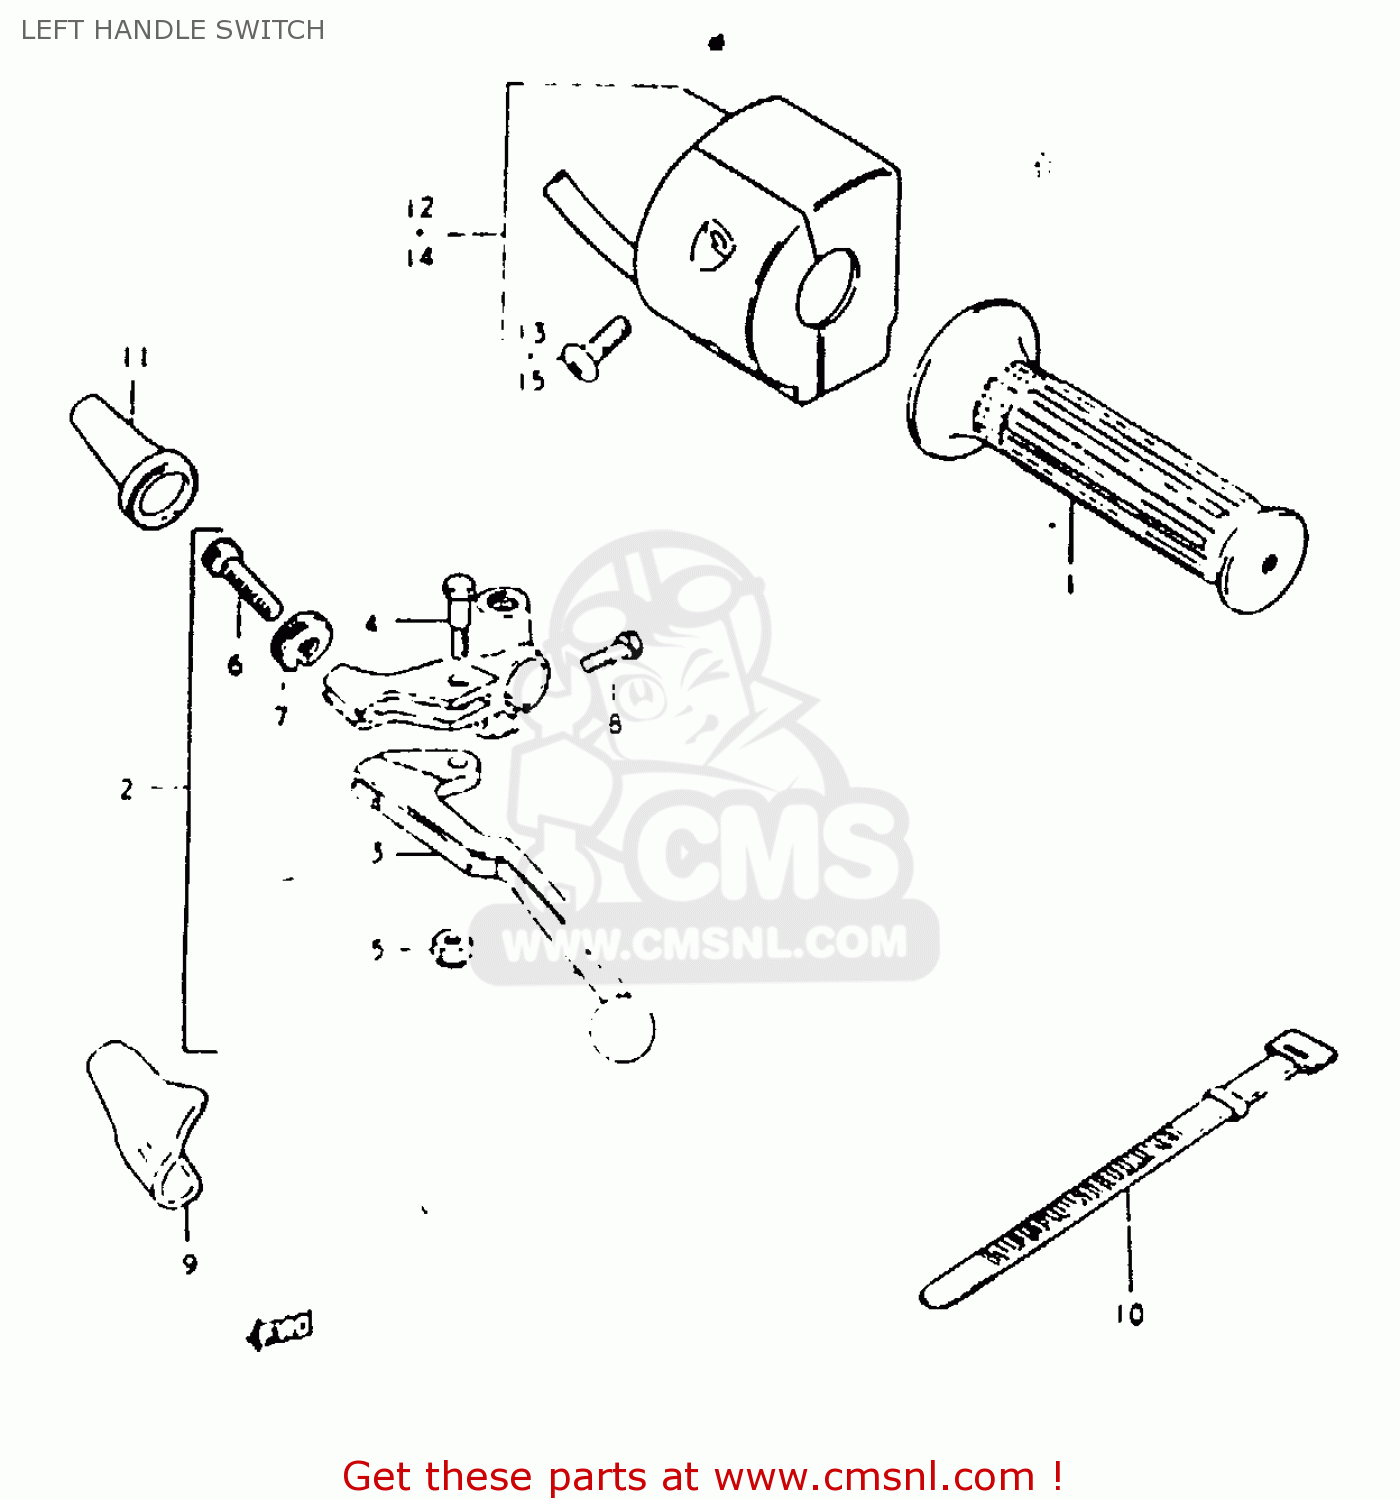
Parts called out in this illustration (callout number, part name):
1	GRIP,LEFT
2	LEVER ASSY, CLUTCH
3	LEVER,CLUTCH
4	BOLT,LEVER
5	NUT 6MM
6	ADJUSTER,CABLE
7	NUT,CABLE ADJUSTER
8	BOLT
9	COVER,CLUTCH LEVER
10	CLAMP(L:120)
11	BOOT,CLUTCH CABLE
12	SWITCH ASSY, HANDLE LH
13	SCREW
